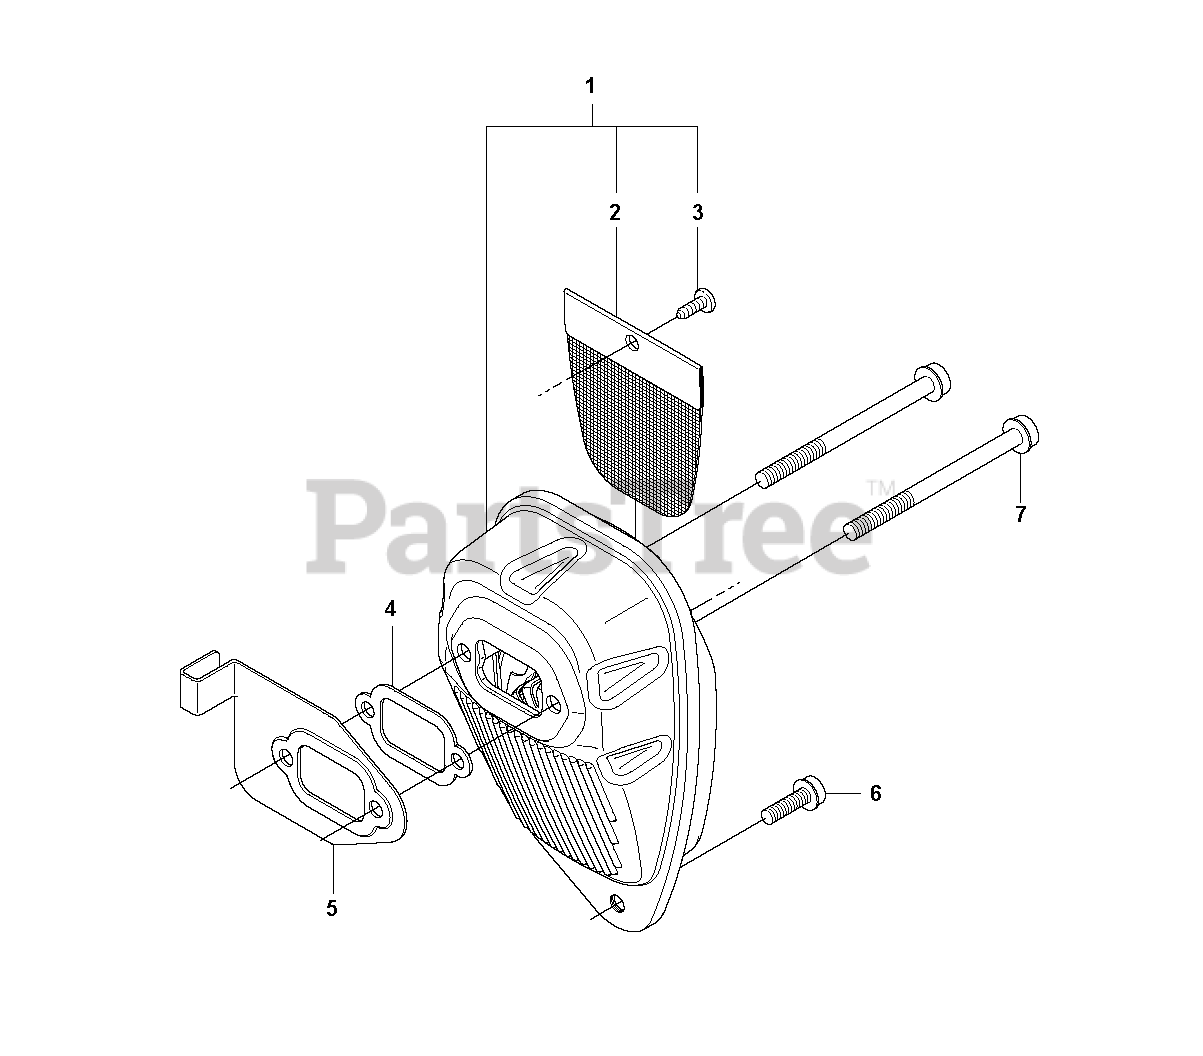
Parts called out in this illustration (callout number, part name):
1	MUFFLER
1	MUFFLER KIT COMPLETE
2	SPARK ARRESTER
3	SCREW
4	GASKET MUFFLER
